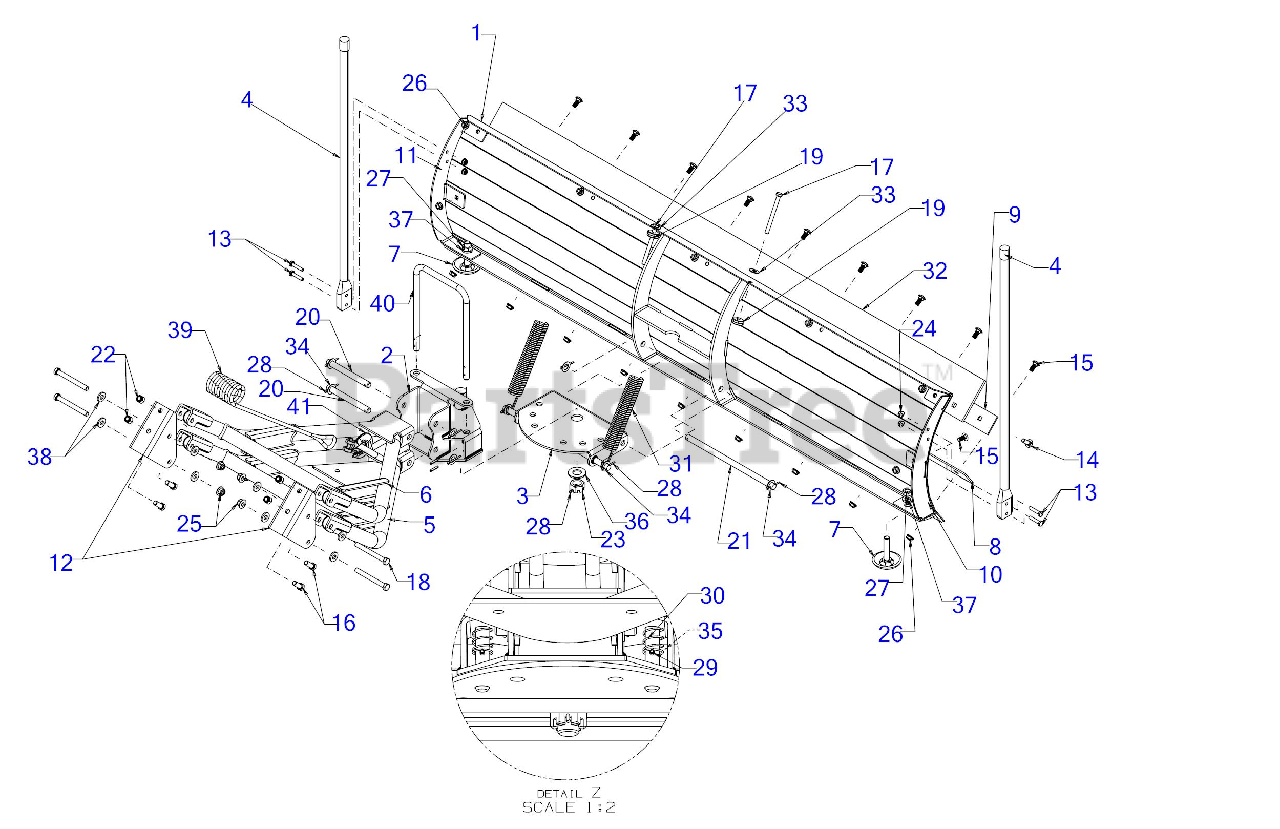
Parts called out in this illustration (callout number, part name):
4	BLADE GUIDE ROD
13	HEX SCREW 1/4-20 x 1.25
14	CARRIAGE BOLT 5/16-18 x 1.00
15	CARRIAGE BOLT 5/16-18 x .75
16	SCREW 3/8-16 x 1 GR5
17	SCREW 5/16-18 x 3.50 GR5
18	SCREW 3/8-16 x 3.50 GR5
19	INSERT SPRING
21	ROD .50 x 10.428"
22	HEX NUT INS L-3/8-16
23	HEX NUT CASTLE 3/4-16
24	FLANGE LOCK NUT
26	HEX FLANGE NUT
27	HEX NUT
28	COTTER PIN
30	COMPRESSION SPRING
31	EXTENSION SPRING
32	58" BLADE TRIM
33	FLAT WASHER
34	FLAT WASHER
35	FLAT WASHER .510 x 1.00 x .060
36	FLAT WASHER
37	LOCK WASHER 1/2
38	FLAT WASHER
39	WINCH CABLE FOR SNOW PLOW 5/16"
40	HANDLE LOCK ROD
41	CLEVIS PIN HOOK
